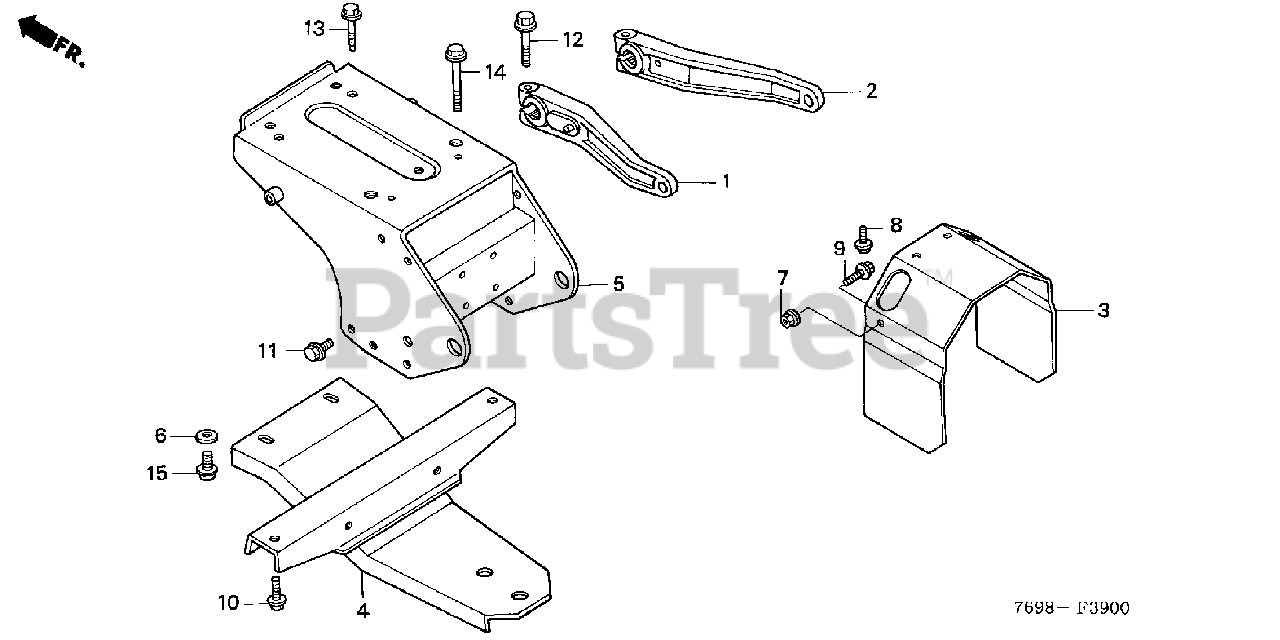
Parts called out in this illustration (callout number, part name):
1	ARM, L. RR. LIFT
2	ARM, R. RR. LIFT
3	SHIELD, RR. P.T.O. MASTER
4	PLATE, DRAWING
5	PLATE, HYDRAULIC CYLINDER MOUNTING
6	WASHER, PLAIN (12MM)
7	NUT, FLANGE (10MM)
8	BOLT, FLANGE (8X14)
9	BOLT, FLANGE (10X20)
10	BOLT, FLANGE (10X22)
11	BOLT, FLANGE (10X25)
12	BOLT, FLANGE (10X40)
13	BOLT, FLANGE (10X50)
14	BOLT, FLANGE (10X70)
15	BOLT, FLANGE (12X30)
